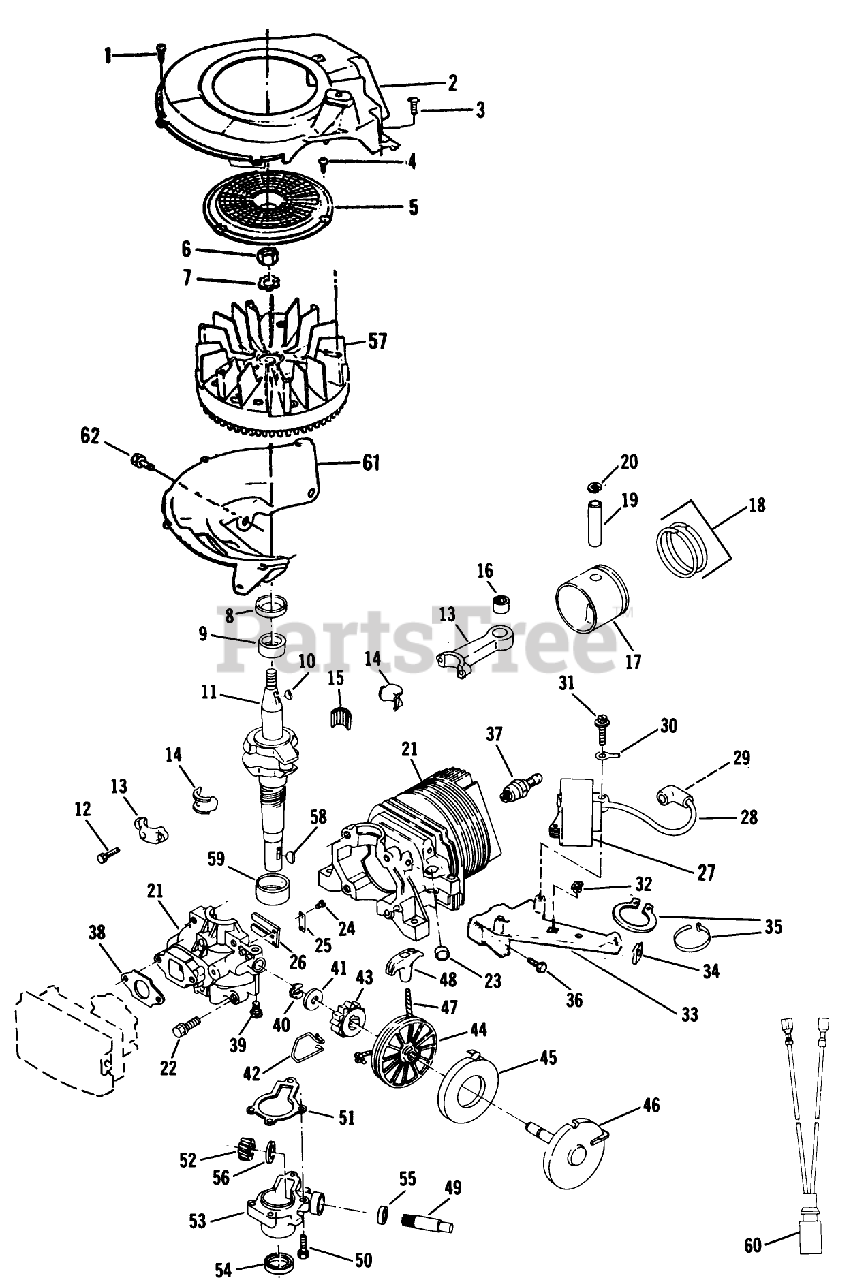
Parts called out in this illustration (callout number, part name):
1	SCREW S
3	SCREW F
4	SCREW F
6	NUT
9	BEARING V
10	KEY
12	SCREW-HSH
14	LINER ASM
16	BEARING AY F
20	RING-RETAINING
22	-Screw-Cover to Crankcase
23	PLUG-CORE VF
25	PLATE-BACKUP, REED
28	HT LEAD&COVER XEV
30	TERMINAL S
32	NUT-CLIP
34	NUT - SPEED S
38	GASKET CARB S
41	WASHER S
42	SPRING F
44	PULLEY STARTER S
48	HANDLE STARTER S
51	GASKET S
52	GEAR, DR SHAFT S
54	SEAL-OIL
55	SEAL S
56	THRUST WASHER
59	BEARING S
60	WIRE HARNESS
61	SHROUD BASE S
62	SCREW-SEMS
